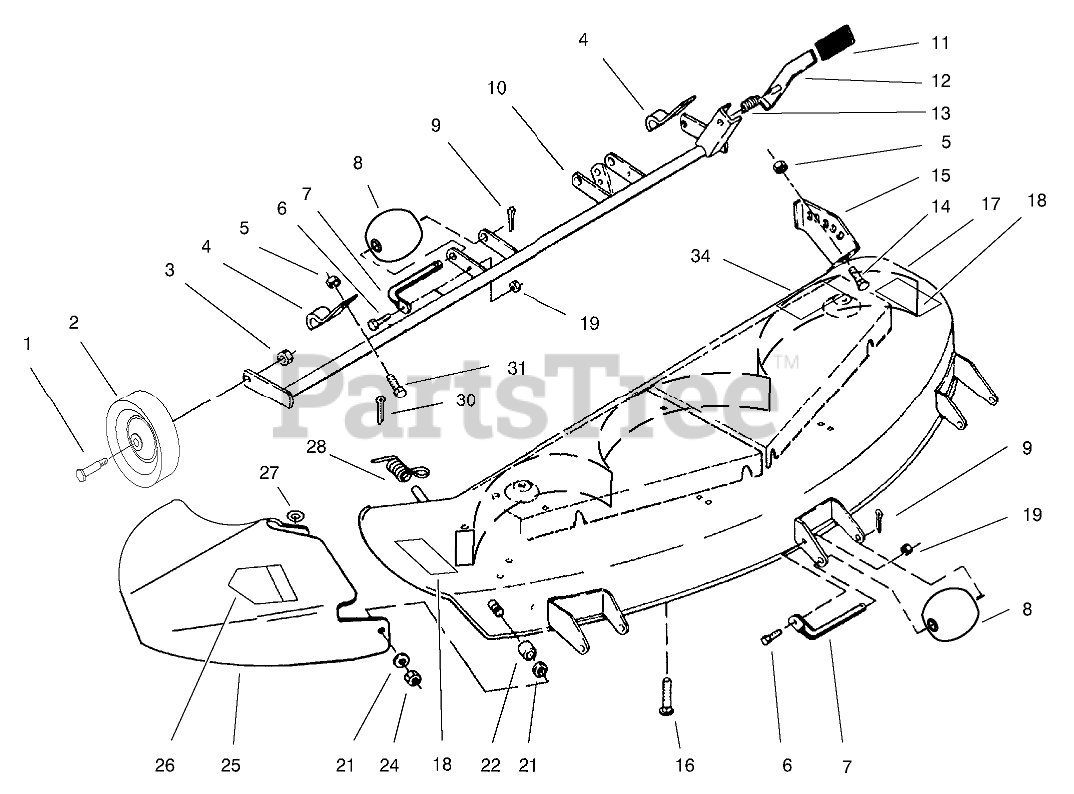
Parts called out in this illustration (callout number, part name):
1	BOLT-SHOULDER
2	WHEEL
3	NUT-HEX
4	BRACKET-PIVOT
5	NUT-LOCK, NI
6	SCREW-HH
7	ROLLER-SHAFT
8	ROLLER
9	PIN-COTTER
10	WA-SUPPORT,GAGE WHL (RED)
12	WLDMT-LEVER (RED)
13	SPRING-COMPRESSION
14	SCREW-HH
15	RH QUADRANT (RED)
16	BOLT-CARR
17	Deck-Assembly (Incl. Ref. #18)
18	DECAL-DANGER
19	NUT-LOCK, NI
21	WASHER
22	BUSHING-PIVOT
24	NUT-HJ
25	Chute Assembly (Incl. Ref. #26)
26	DECAL-DANGER
27	WASHER-FLAT
28	SPRING-DEFLECTOR
30	PIN-COTTER
31	BOLT-CARR
34	DECAL-HEIGHT & BELT
